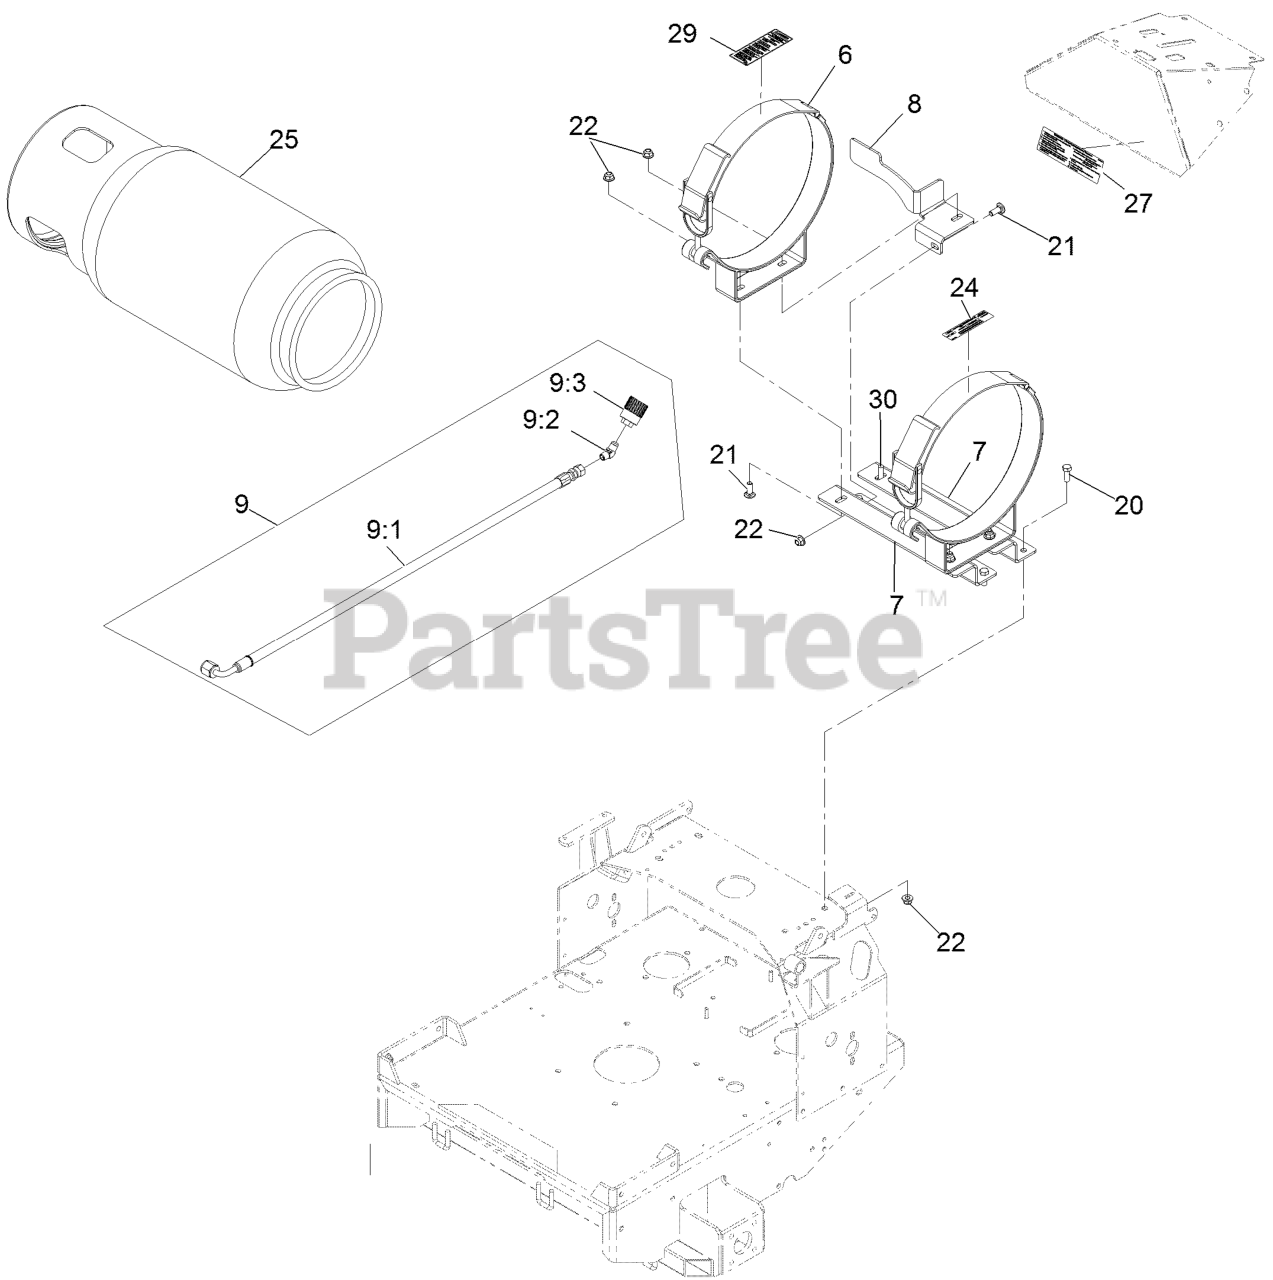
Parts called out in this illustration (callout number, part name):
6	BRACKETS, LPG TANK - HORI
7	RISER, LPG TANK
8	BRACKET, LPG TANK INDEX
9	Asm, Lpg Fuel Hose
9:1	LPG FUEL HOSE ASM
9:2	ELBOW-45 DEG
9:3	CONNECTOR-LPG TANK, LH TH
20	SCREW-HH
21	SCREW-CARR
22	NUT-HF, NI
24	DECAL,LPG TANK SPEC HORIZ
25	TANK,LPG 33LB
27	DECAL-TANK REPLACEMENT
29	DECAL-LPG WARNING
30	BOLT-CARR
